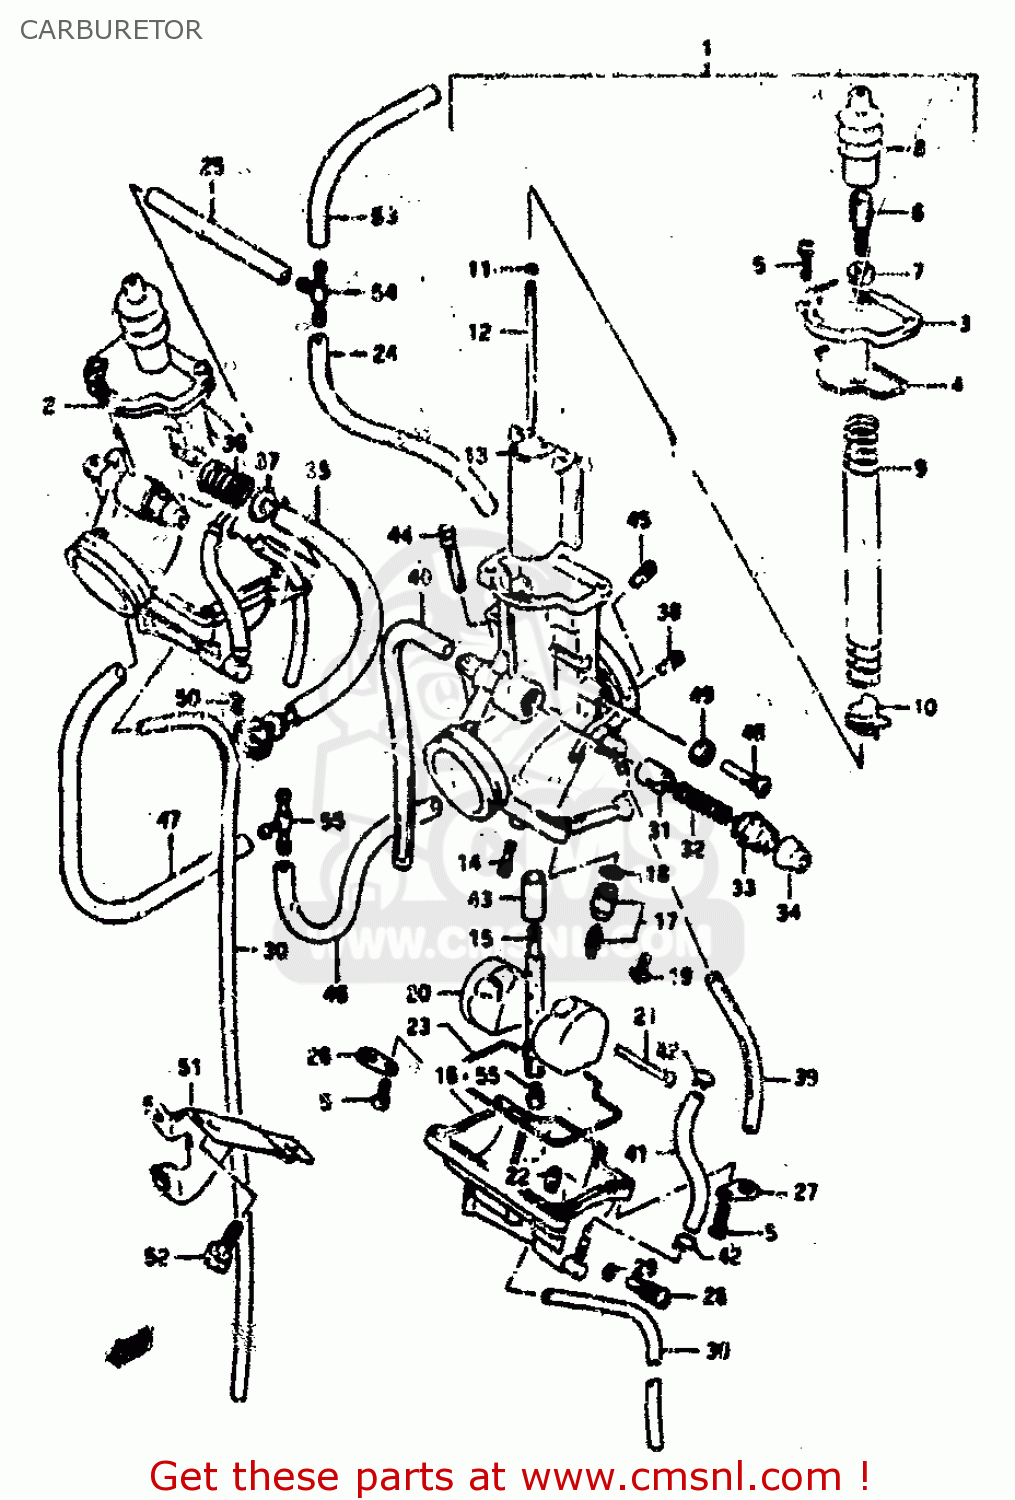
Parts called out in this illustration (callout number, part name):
1	CARBURETOR ASSY, LH
2	CARBURETOR ASSY, RH
3	CAP, TOP
4	O RING,TOP CAP
5	SCREW
6	ADJUSTER,CABLE
7	NUT
8	CAP,CABLE ADJUSTER
9	SPRING
10	RING
11	CLIP,NEEDLE
12	NEEDLE,JET
13	VALVE,PISTON(CA:1.5)
14	JET,PILOT 20
15	JET,NEEDLE(O-8)
16	JET,MAIN(270)
17	VALVE ASSY,NEE
18	O-RING,NEEDLE VALVE
19	SCREW
20	FLOAT
21	PIN,FLOAT
22	JET,MAIN(55)
23	GASKET,FLOAT CAHMBER (NAS)
24	HOSE
25	HOSE
26	PLATE,CARBURETOR
27	PLATE
28	PLUG,DRAIN
29	O RING
30	HOSE(3X5X650)
31	PLUNGER,STARTER
32	SPRING
33	HOLDER,GUIDE
34	CAP
35	ADJUSTER,THROTTLE STOP
36	SPRING
37	WASHER
38	JET,AIR(1.3)
39	HOSE(3X5X650)
40	HOSE
41	HOSE SET
42	CLIP
43	RING
44	FILTER
45	JET,AIR(0.6)
46	HOSE
47	HOSE
48	SCREW,ADJUSTER
49	NUT
50	E RING
51	BRACKET,ADJUSTER
52	BOLT
53	HOSE
54	NIPPLE
55	JET,MAIN(230)
